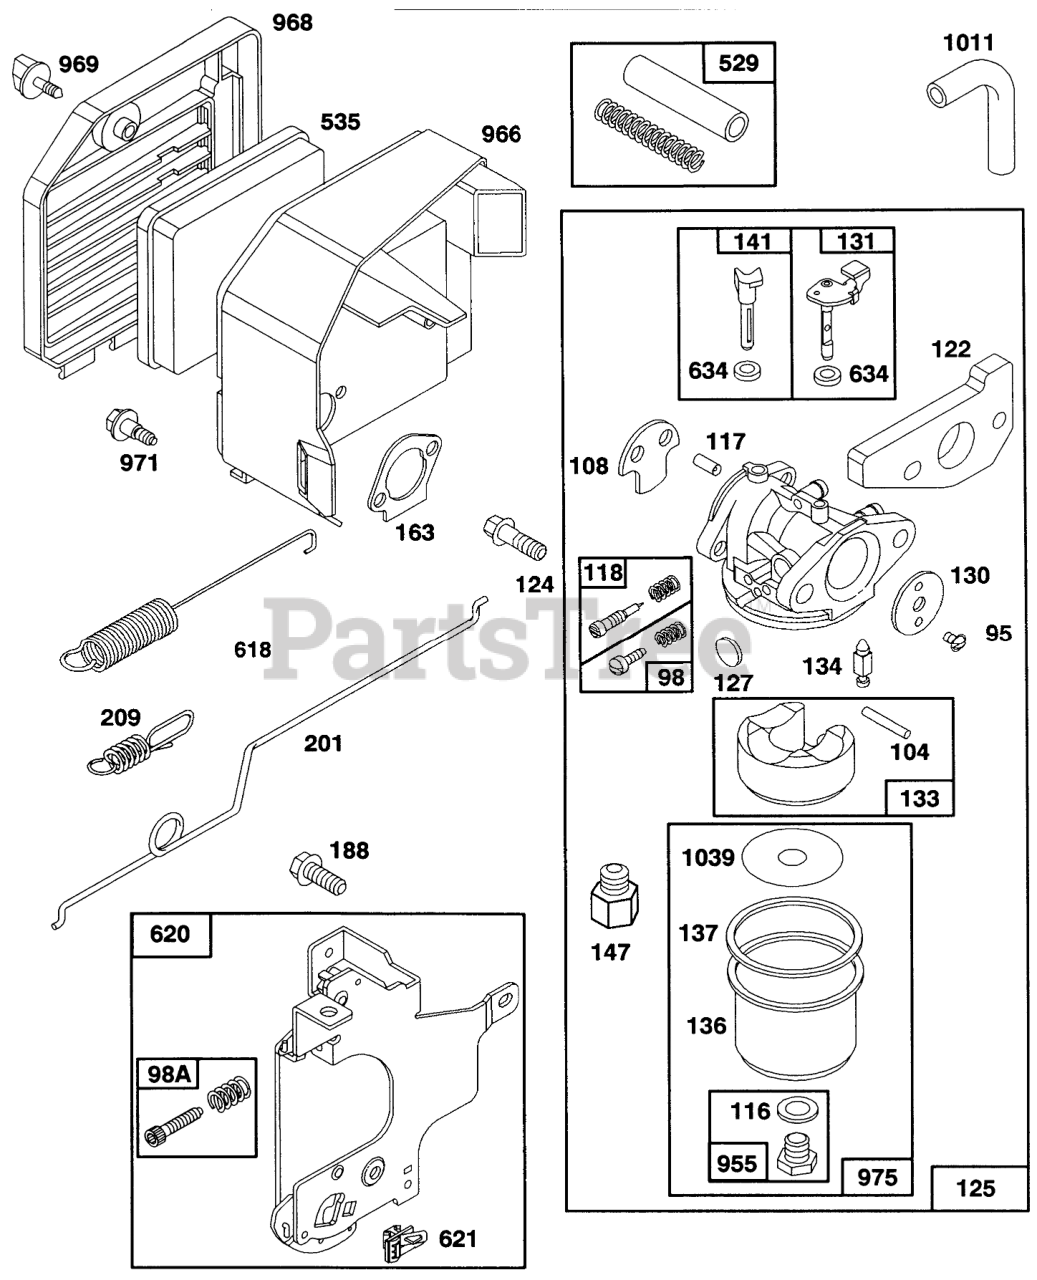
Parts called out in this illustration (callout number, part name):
95	SCREW - ROUND HEAD
98	IDLE ADJUSTING SCREW
98A	SPEED ADJUST. SCREW ASM
104	FLOAT HINGE PIN
108	CHOKE VALVE
116	SEALING GASKET
118	VALVE KIT - NEEDLE
122	ADAPTER ASSEMBLY
124	HEX HEAD SCREW
125	CARBURETOR ASSEMBLY
130	THROTTLE VALVE
131	THROTTLE SHAFT
133	FLOAT-CARBURETOR
134	Valve-Float (Includes Seat)
136	FLOAT BOWL
137	FLOAT BOWL GASKET
141	CHOKE SHAFT
147	JET ADAPTER
163	AIR CLEANER GASKET
188	SCREW - SEM
201	GOVERNOR LINK
209	GOVERNOR SPRING
529	BREATHER TUBE
535	FILTER ELEMENT
618	RETURN SPRING
620	CARBURETOR BRACKET
621	STOP SWITCH
634	SEAL WASHER
955	HEX HEAD SCREW
966	AIR CLEANER BASE
968	AIR CLEANER COVER
969	AIR CLEANER SCREW
971	AIR CLEANER SCREW
975	CARBURETOR BOWL ASM
1011	VENT TUBE
1039	FLOAT LIMITER
